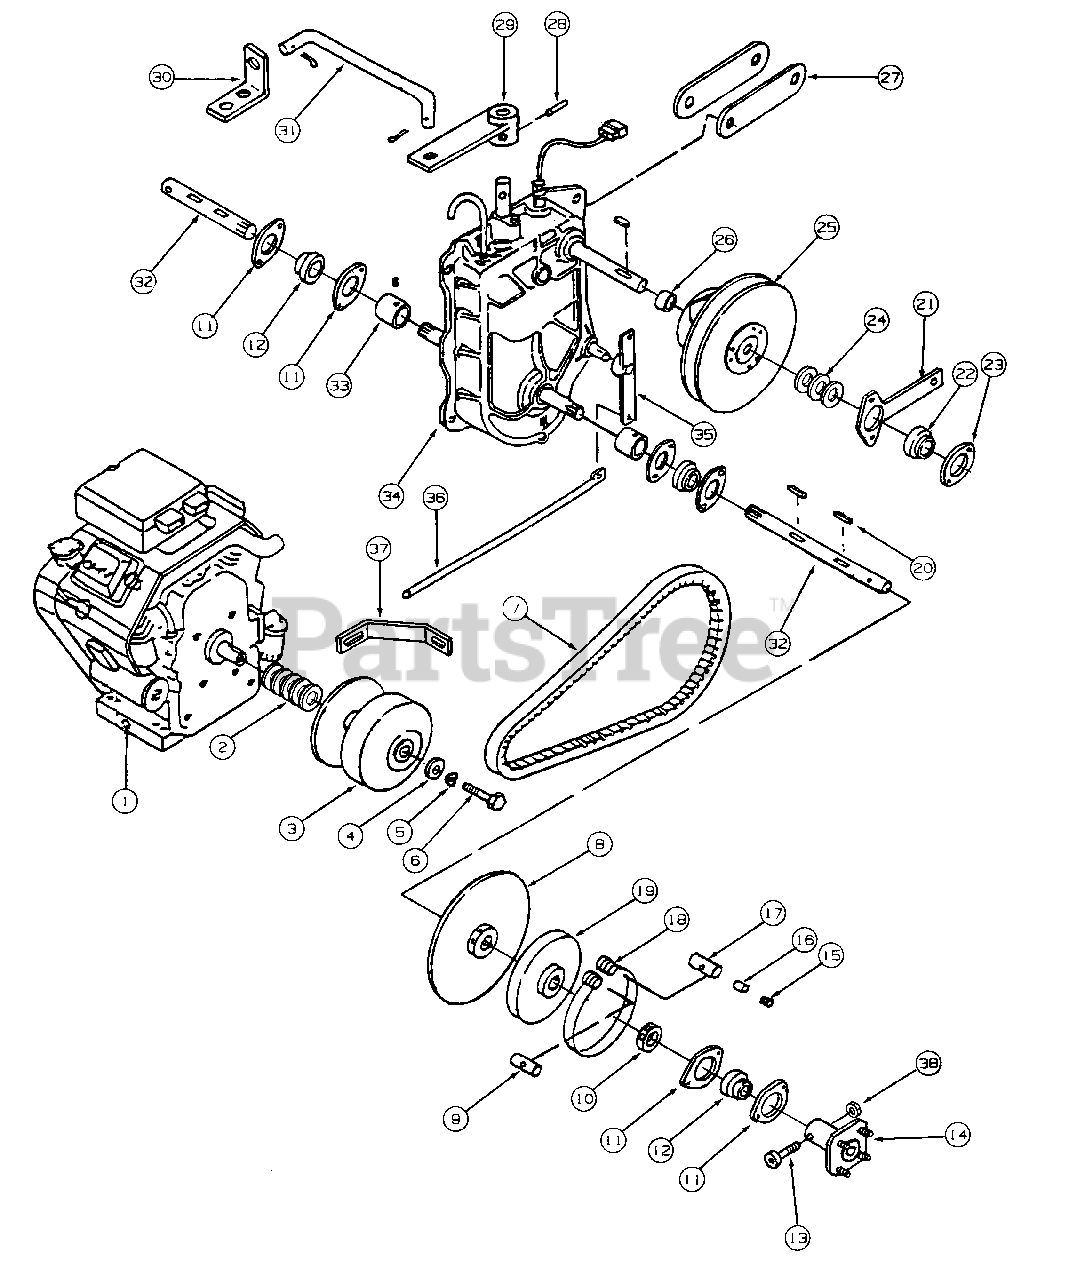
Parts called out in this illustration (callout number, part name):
1	Engine, Vanguard, 16 HP
2	Washer, 1 X 1-1/2 10 Ga
3	Clutch, Drive, 40 Series
4	Washer, .38 X 1.25 X 1.2
5	Lockwasher, Helical Spring
6	Screw, Hex Hd Cap, .38-24 UNF X 1.5
7	Belt, Drive
8	Disc & Hub, Brake
9	Guide, Brake Wire
10	Collar, Split Lock
11	Flange, Bearing
12	Bearing, Ball, 1"
13	Screw, Skt Hd Cap, .44-14 UNC X 2.0
14	Hub Assy, Rear
15	Screw, Set, .25-20 X .25
16	Pad, Brake Wire
17	Stop, Brake Wire
18	Band, Parking Brake
19	Drum, Parking Brake
20	Key, Woodruff, Hy-Pro #809
21	Support, Shaft Brace
22	Bearing, Ball, 3/4
23	Flange, 3/4
25	Converter, Torque, 40 Series
27	Strap, Mtg
28	Pin, Roll, .25 X 1.5 HBK
29	Arm, Shift Actuator
30	Bracket, Shift
31	Rod, Shift
32	Axle, Shaft
33	Coupler, Splined
34	Transaxle, KT30A
35	Arm, Diff Lock
36	Rod, Diff Lock
37	Bracket, Engine Support
38	Locknut, .44-14 UNC
